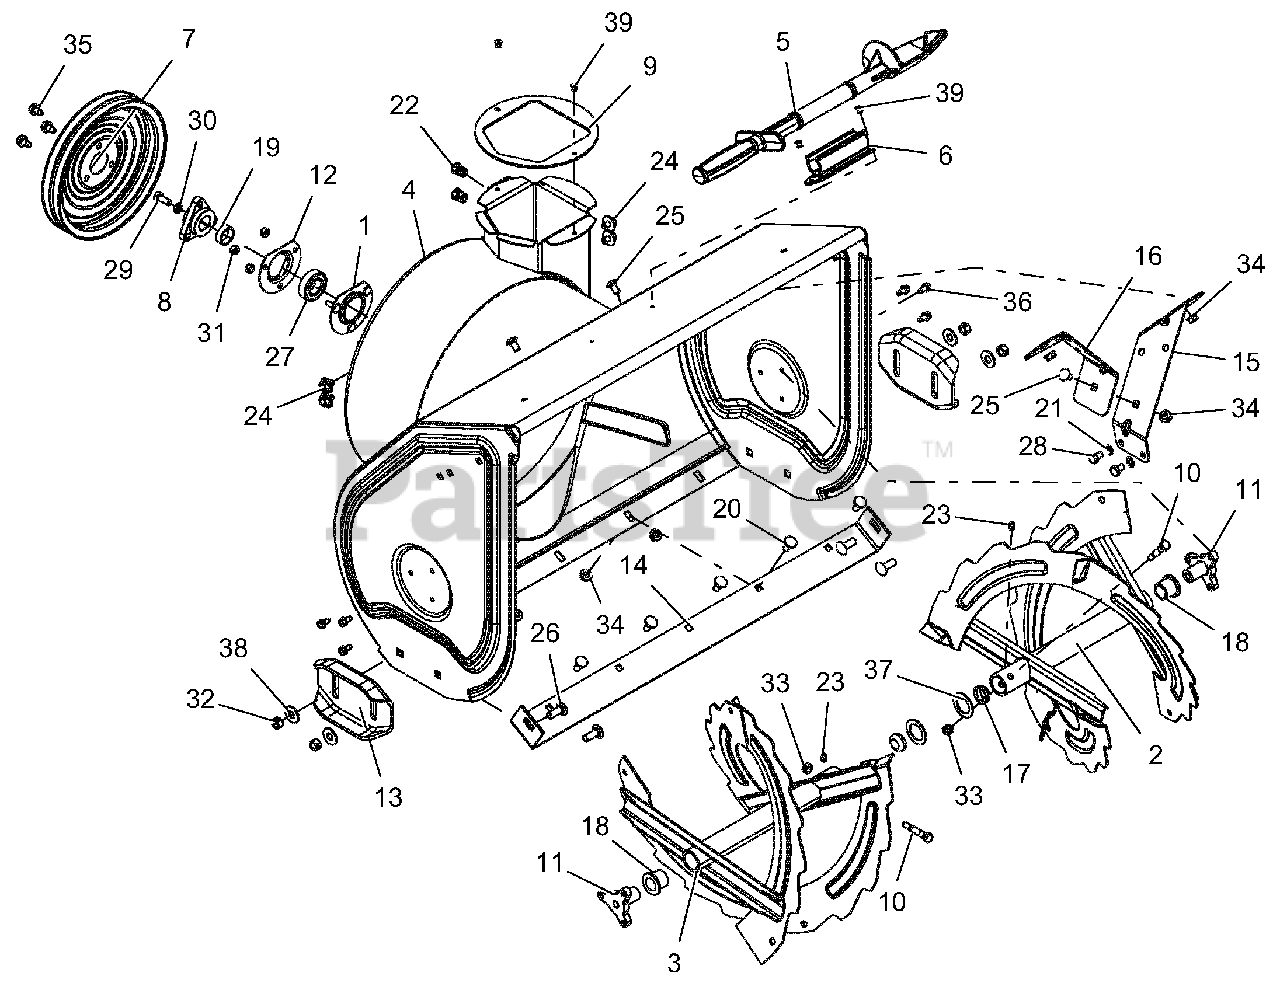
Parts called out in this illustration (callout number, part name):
1	BEARING FLANGE
2	RAKE, LH W/ZERK - 28"
3	RAKE, RH W/ZERK - 28"
4	BLOWER HOUSING, 28"
5	DEVICE, SNOW CLEAN OUT
6	MOUNT, SNOW CLEAN OUT
7	PULLEY, SPIN FORM DUAL GROOVE
8	PULLEY HUB, D-BORE .87 DELUXE
9	BAFFLE, DISCHARGE NECK
10	SHEAR BOLT SERVICE ASSEMBLY
11	SUPPORT, RAKE BUSHING
12	BEARING FLANGE
13	SKID SHOE, REVERSIBLE - ORANGE
14	BLADE, SCRAPER - 28"
15	BRACKET, GEARCASE SUPPORT - LH
16	BRACKET, GEARCASE SUPPORT - RH
17	PLUG, RAKE TUBE
18	BSHG-FLG, NY.778 ID X 1.018 OD
19	BSHG-SPCR .895IDX1.065ODX.353
20	BOLT, MODIFIED HEAD CARRIAGE
21	@WSHR-LK-EXT.326X.599X.031YWZC
22	NUT, THREADED INSERT .38-16
23	ZERK,FITTING .25X.125 DRIVE IN
24	SCR-TAP.31-18X.50 HWH TR YWZ
25	BLT-RDHDSQSHNK.31-18X.62 YZ-LK
26	@BLT-RDHDSHSQNK.38-16X1.0 G5YZ
27	BRG-BALL .876 X 1.750 X .50
28	@BLT-HEX .31-18X.50 GR5 YWZC
29	BLT-HEX .31-24X.75 YWZC GR5
30	WSHR-LK .312X.097 HVY YWZC
31	@NUT-LK-CTR .25-20 YWZC
32	@NUT-LK-CTR .38-16 YWZC
33	@NUT-LK-CTR .31-18 YWZC
34	@NUT-LK-TOP-FLG .31-18 YWZC
35	@SCR-TAP .31-18X.50 HWH TR YWZ
36	SCR-TAP .25-20X.50 HWH TR YWZ
37	WSHR-FL-STL 1.010X1.505X.062YZ
38	@WSHR-FL-STL.438X1.00X.083 YWZ
39	RVT-POP .187 YZ
